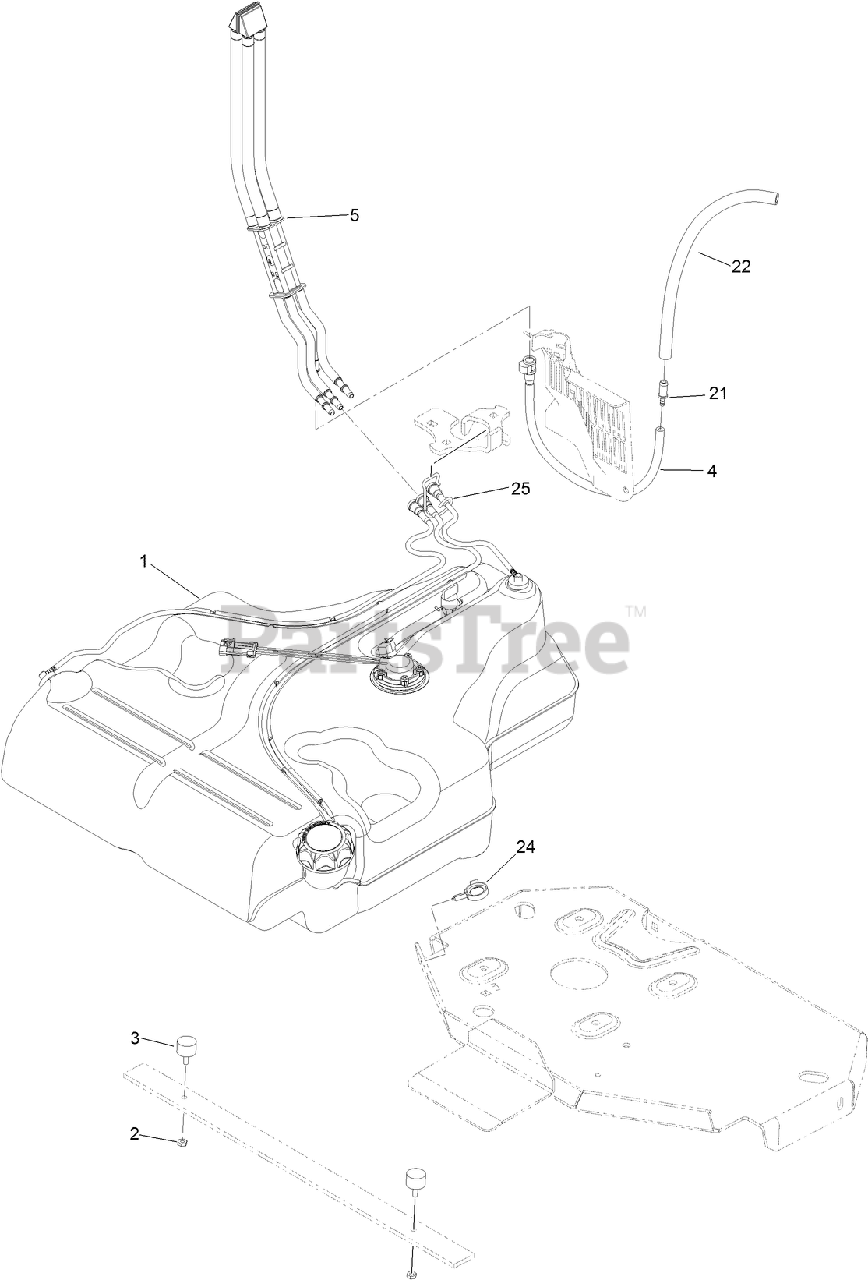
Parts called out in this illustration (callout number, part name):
1	FUEL TANK ASM
2	NUT-JAM
3	BUMPER-RUBBER (W/ STUD)
4	HOSE ASM
5	FUEL MANIFOLD VENT ASM
21	FITTING-STRAIGHT
22	HOSE-FUEL
24	CLAMP-HOSE
25	RETAINER-LINE, VAPOR
